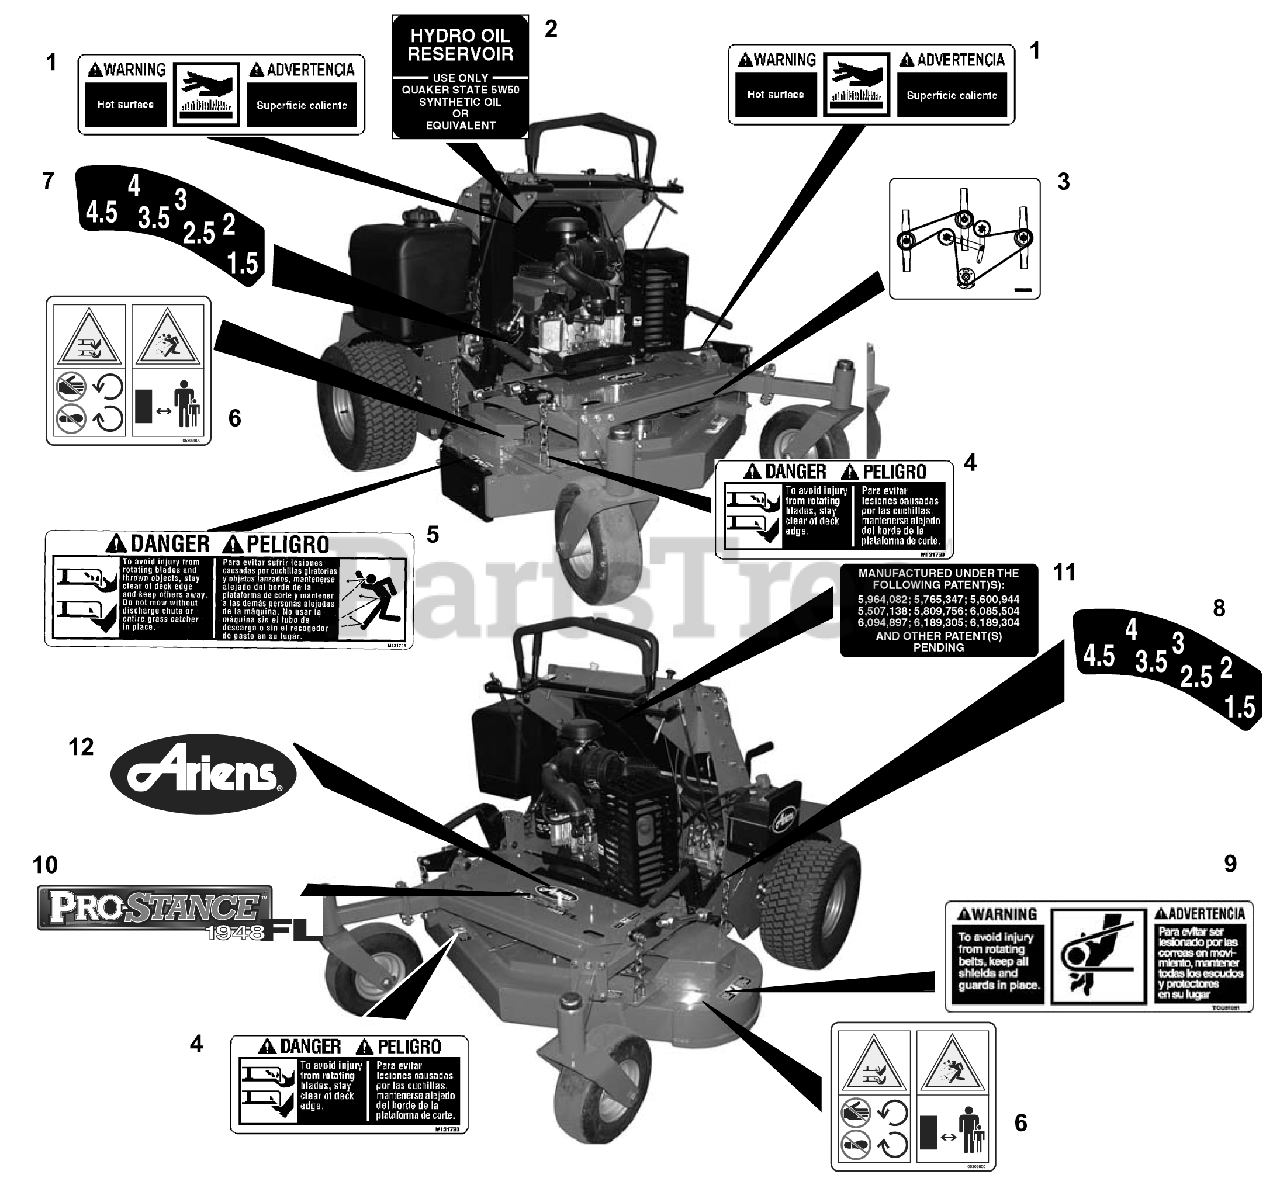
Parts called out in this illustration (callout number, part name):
1	DECAL, WARNING-HOT SURFACE (RE
2	DECAL, HYDRO OIL RESERVOIR
3	DECAL, BELT PATH, SUPER SURFER
4	DECAL, DANGER-BLADE CONTACT
5	DECAL, DANGER-THROWN OBJECTS
6	DECAL, CE DECK
7	DECAL, CUT HEIGHT, RH
8	DECAL, CUT HEIGHT, LH
9	DECAL, DANGER-ROTATING BELTS
10	DECAL, PRO-STANCE 1948FL
11	DECAL, PATENT
12	DECAL, ARIENS
